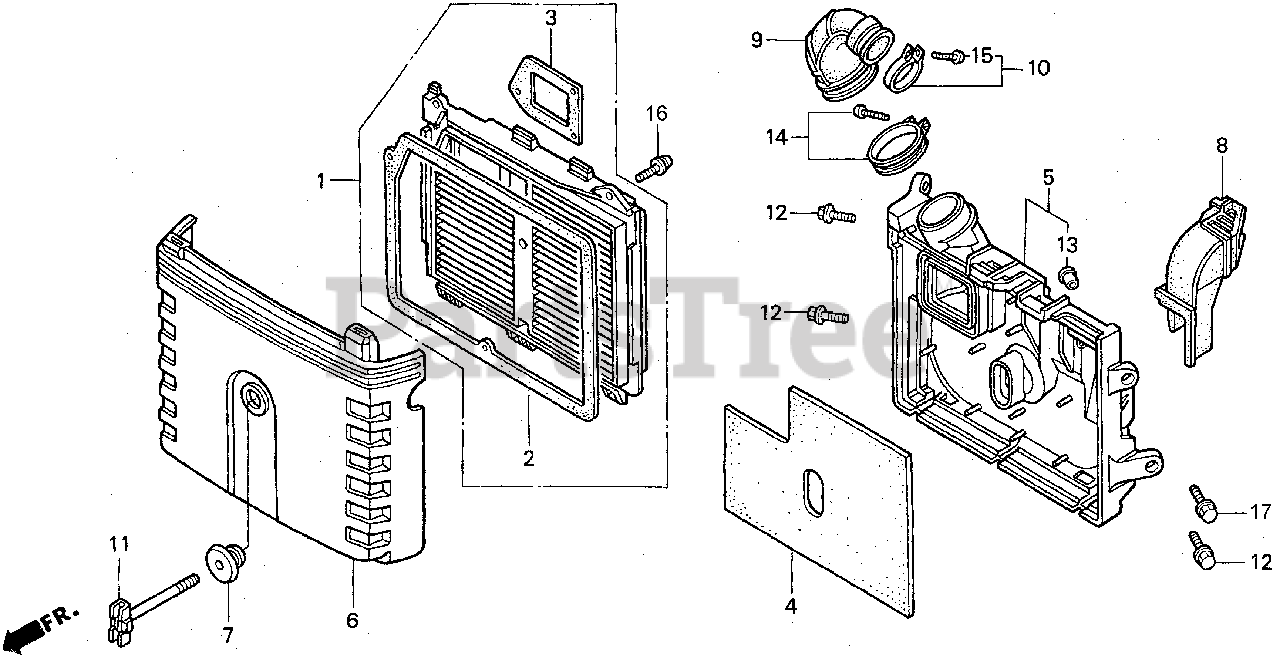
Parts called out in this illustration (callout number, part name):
1	ELEMENT SET, AIR CLEANER
2	GASKET A, ELEMENT
3	GASKET B, ELEMENT
4	FILTER (OUTER)
5	HOUSING, AIR CLEANER
6	COVER, AIR CLEANER
7	GROMMET, AIR CLEANER
8	HOSE, AIR CLEANER
9	TUBE, AIR CLEANER CONNECTING
10	BAND, AIR CLEANER CONNECTING TUBE
11	BOLT, AIR CLEANER
12	BOLT, FLANGE (6X23)
13	COLLAR, AIR CLEANER HOUSING
14	BAND, CARBURETOR
14	BAND, AIR CLEANER CONNECTING TUBE (50)
15	SCREW, PAN (4X20)
16	SCREW, PAN (4X25)
17	SCREW-WASHER (5X16)
18	BOLT, FLANGE (6X18)
